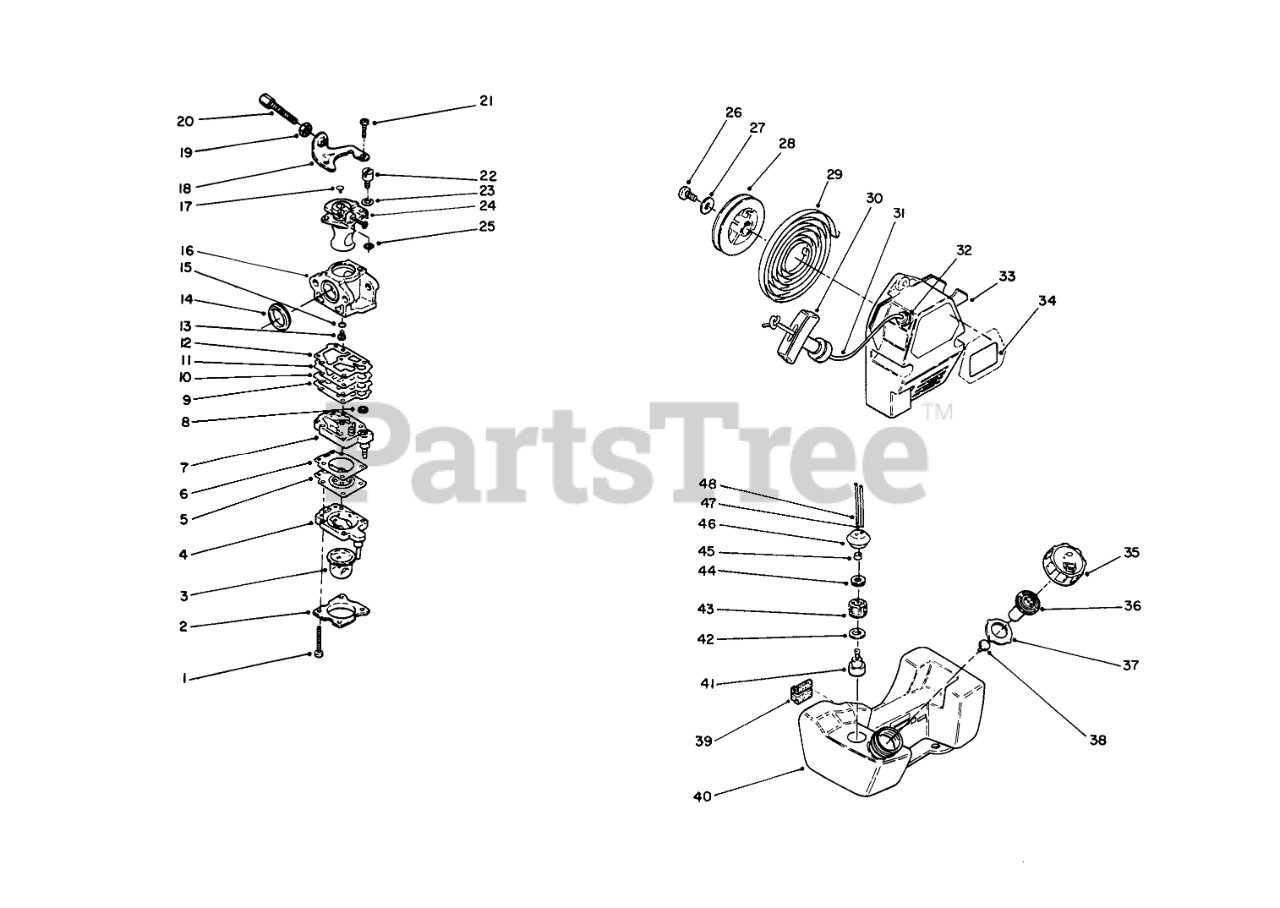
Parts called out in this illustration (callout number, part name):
1	SCREW
2	Cover-Primer
3	PRIMER PUMP
4	PRIMER BODY
5	DIAPHRAGM
6	DIAPHRAGM GASKET
7	Body Ass-y-Pump (Incl. Ref. #8)
8	SCREEN
9	PUMP GASKET
10	Plate
11	DIAPHRAGM
12	DIAPHRAM GASKET
13	Jet-Main #42
14	RUBBER CARB GASKET
15	MAIN JET O-RING
16	Body-Carburetor (Ref.)
18	BRACKET
19	LOCKNUT
20	ADJUSTING SCREW
21	SCREW
22	Holder-Wire
23	WASHER
24	THROTTLE VALVE
26	SCREW
27	Washer
29	SPRING
30	Knob-Starter
31	Rope-Recoil
32	GUIDE
33	RECOIL CASE
34	Decal-Toro
35	FUEL TANK CAP
36	BREATHER VALVE
37	PACKING
40	Tank Assembly-Fuel (Incl. Ref. #35-38 & 41-48)
41	Weight-Filter
43	Filter-Fuel
44	Washer-Seal
45	COLLAR
46	FUEL TANK GROMMET
47	TUBE, FUEL
48	RETURN FUEL HOSE
